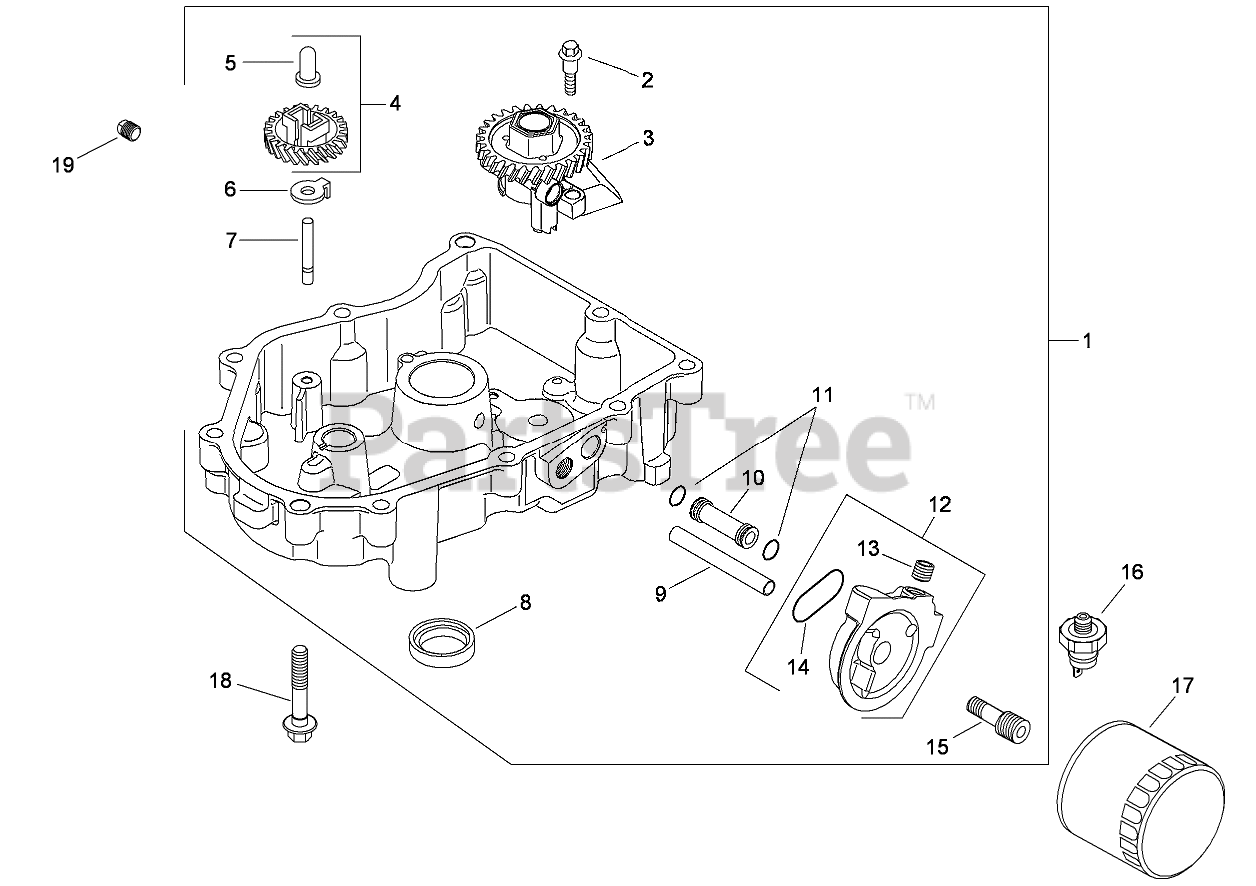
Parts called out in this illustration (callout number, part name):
1	OIL PAN ASM (INCLUDES 2-15)
2	SCREW-SHOULDER, THD FRM (M6x1.0x26.5)
3	OIL PUMP ASM
4	GOVERNOR GEAR W/PIN KIT (INCLUDES 5)
5	PIN-REGULATING, GOVERNOR
6	TAB-LOCKING
7	SHAFT-GEAR, GOVERNOR
8	SEAL-OIL
9	TUBE-FEED, OIL (FILTER TO PAN)
10	TUBE-FEED, OIL (PAN TO FILTER)
11	O-RING (OIL PICK-UP)
12	OIL FILTER ADAPTER KIT (INCLUDES 13, 14)
13	PLUG-PIPE, COUNTERSUNK (1/8)
14	O-RING (OIL FILTER ADAPTER)
15	NIPPLE-FILTER, OIL
16	SWITCH-PRESSURE, OIL
17	FILTER-OIL
18	SCREW-FLANGE (M8X1.25X45)
19	PLUG-PIPE, SQ HD (3/8)
